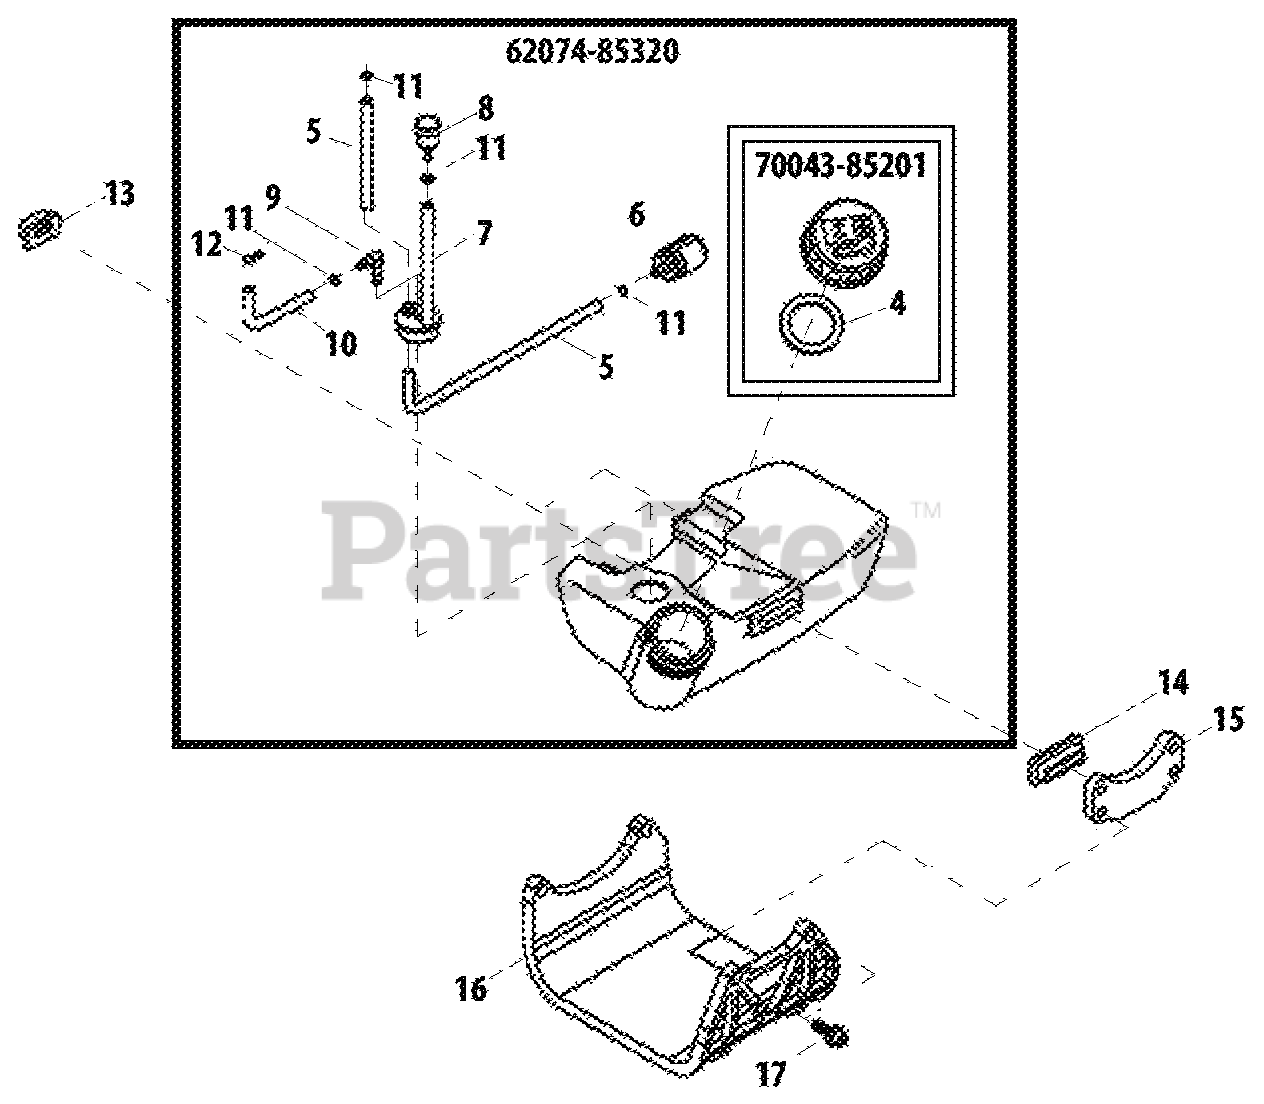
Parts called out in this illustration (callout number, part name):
4	GASKET, CAP
5	PIPE - FUEL
6	FILTER, FUEL
7	GROMMET
8	VENT, FUEL TANK
9	CONNECTOR, PIPE
10	PIPE - RETURN
11	RING, RETAINING - 6
12	CLIP - SPRING
13	CUSHION, TANK
14	CUSHION, TANK
15	BRACKET, FUEL TANK
16	GUARD, FUEL TANK
17	SCREW - 5X20
6207485320	FUEL TANK ASSY
7004385201	CAP ASSY
